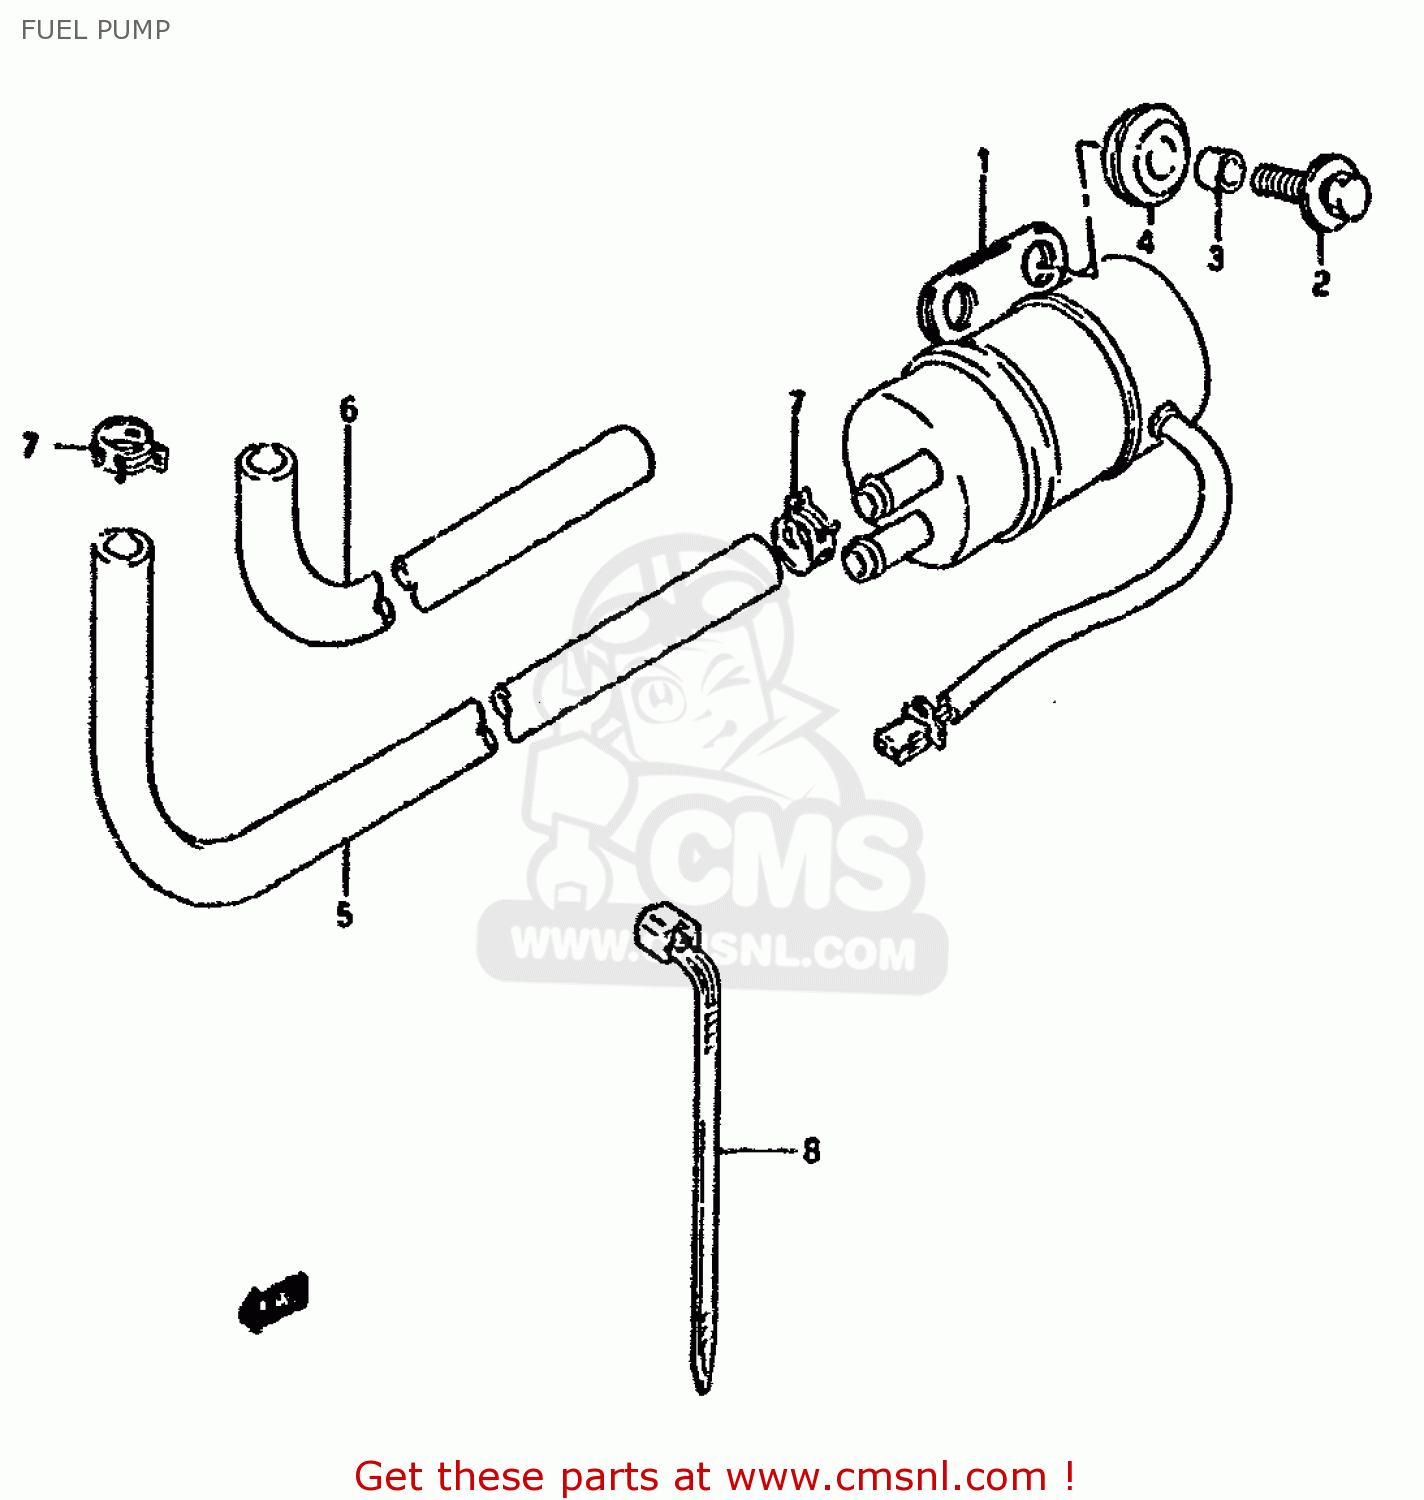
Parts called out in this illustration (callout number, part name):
1	PUMP ASSY,FUEL
2	BOLT(6X20)
3	SPACER (6.1X9X9)
4	CUSHION
5	HOSE (7X13X1000)
6	PROTECTOR(14.5X15.5X600)
7	CLIP
8	CLAMP(L:125)
